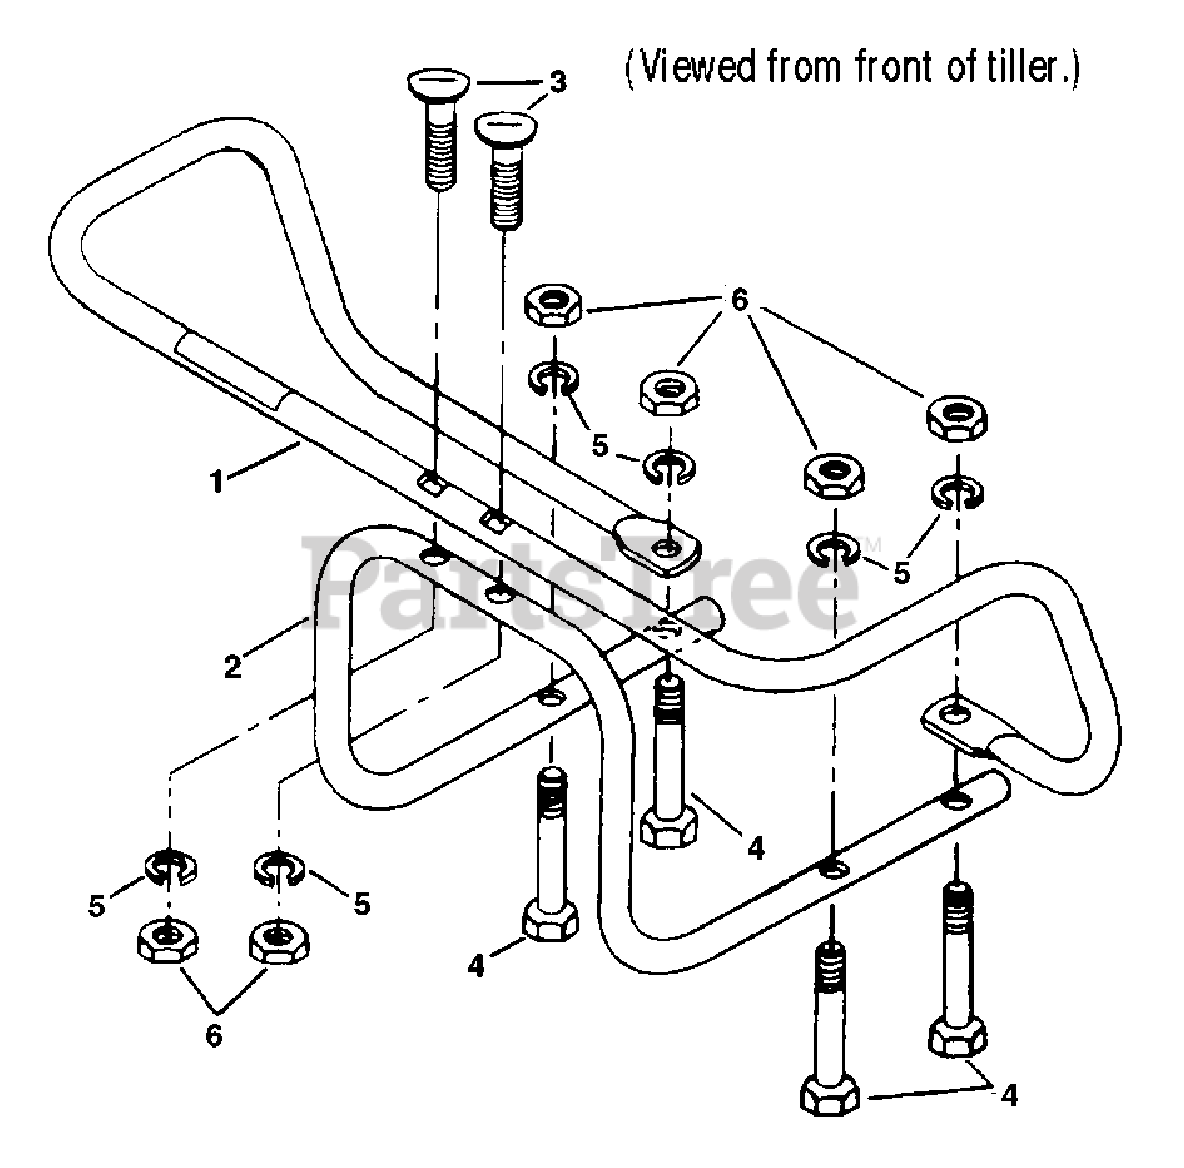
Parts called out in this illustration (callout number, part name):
1	Bumper, Top Section
2	Bumper, Bottom Section
3	Curved Hd. Screw, 5/16-18 x 2 (special)
4	Hex Hd. Screw, 5/16-18 x 2-1/2
5	Lockwasher, 5/16
6	Hex Nut, 5/16-18
